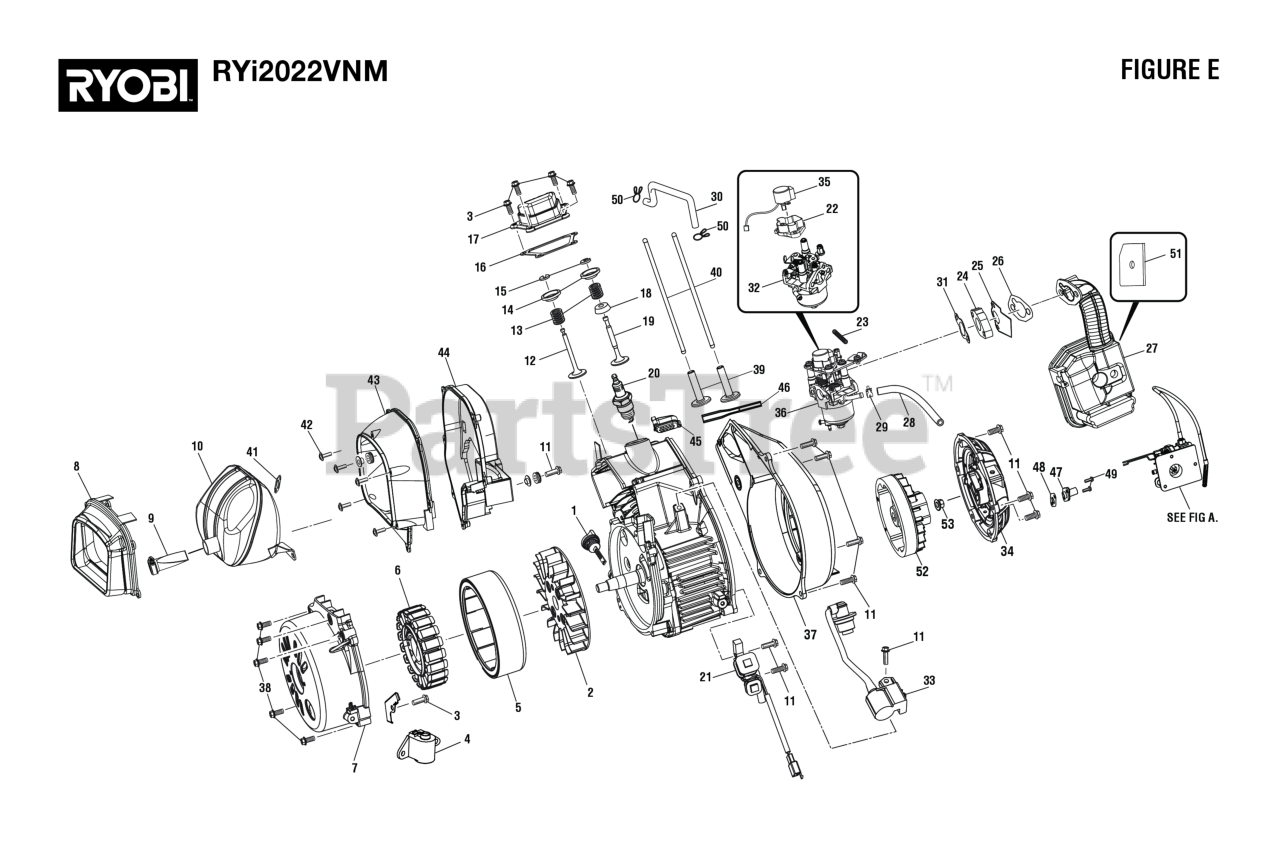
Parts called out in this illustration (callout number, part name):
1	Oil Dipstick
3	Bolt (M6 x 12 mm)
4	Low Oil Sensor
7	Alternator Cover
8	Muffler Heat Shield
9	Spark Screen
11	Bolt (M6 x 16 mm)
12	Exhaust Valve
13	Valve Spring
15	Valve Lock Clamp
16	Gasket (Over Head Cover)
17	Over Head Cover
18	Inlet Valve Spring Seat
19	Inlet Valve
20	Spark Plug
21	RPM Sensor
22	Governor Motor Housing
23	Compression Spring
24	Thermal Insulation Seat (Carburator)
25	Paper Gasket
26	Air Box Gasket
27	Air Filter Assembly
28	Fuel Hose (6 mm)
29	Fuel Line Clamp (7/16 in., BM903611)
30	Breather Hose
31	Gasket (Connection Block)
32	Carburetor
33	Ignition Coil
34	Engine Recoil
35	Stepper Motor
36	Carburetor Assembly (Inc. Key Nos. 22, 32 and 35)
37	Engine Cover
38	Bolt (M6 x 30 mm)
39	Lifter Valve
40	Pushing Rod
41	Gasket (Muffler)
43	Muffler Cover 1
44	Muffler Cover 2
45	Fill Valve Assembly
46	Breather Pipe
47	Ring Flange
48	Oil Ring
49	Bolt (M5 x 12 mm)
51	Air Filter
52	Flywheel
53	Flywheel Nut
